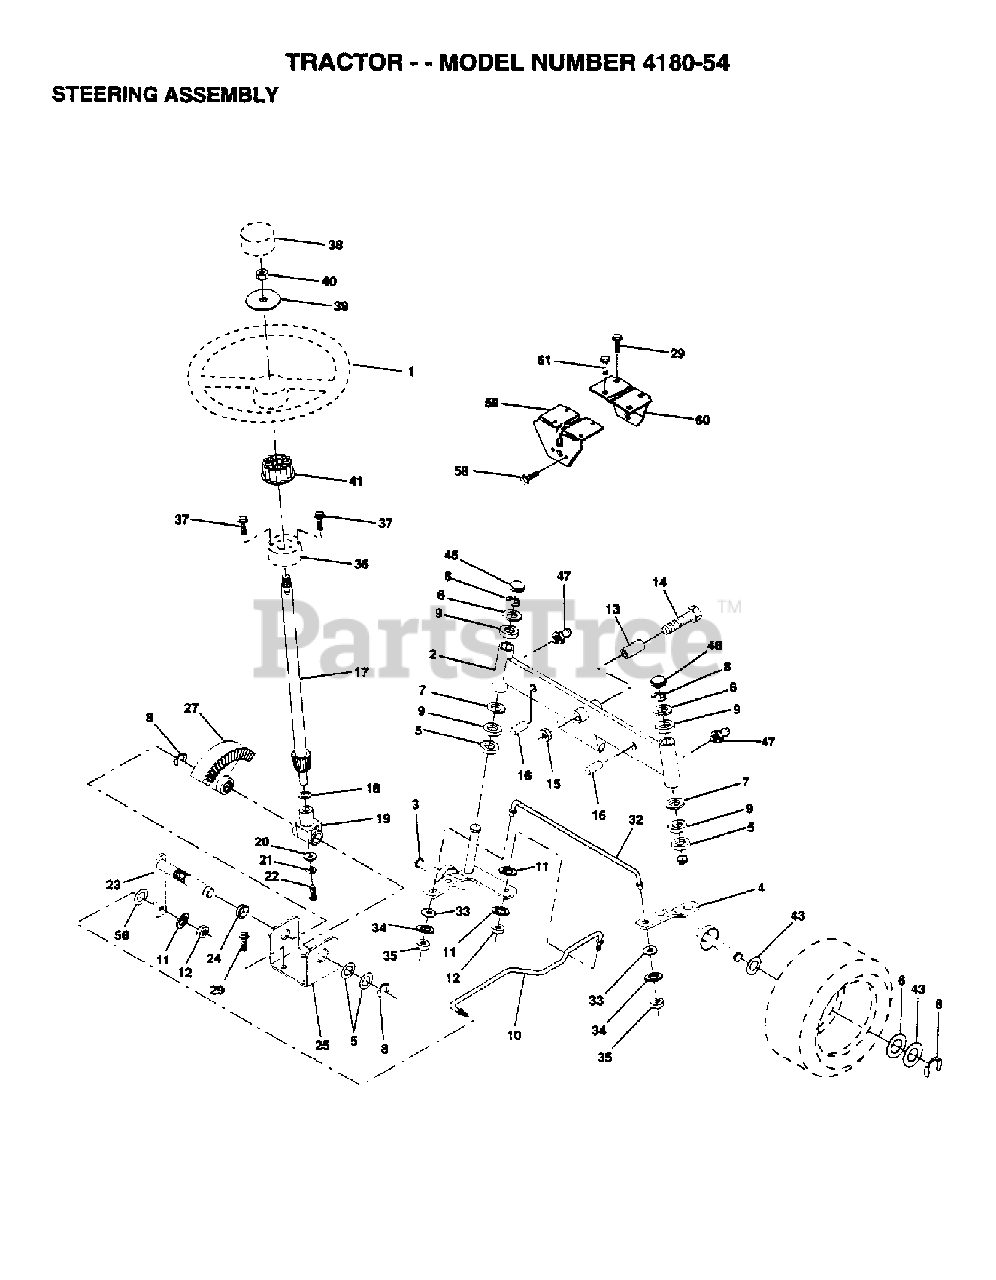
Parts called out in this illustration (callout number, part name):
1	Steering Wheel
2	AXLE ASSY
5	WASHER THRUST
8	RING CLIP
9	BEARING.STEERING.COLUMN
10	DRAG LINK
11	WASHER, LOCK 3/8
12	NUT
15	LOCK NUT
17	SHAFT ASS'Y STEER
18	THRUST WASHER
19	SHAFT,SUPPORT
20	WASHER
21	LOCKWASHER
23	SHAFT,PITMAN
24	NYLINER T (7283A)
25	BRKT,STEERING
27	GEAR.SECTOR
33	WASHER M
34	LOCKWASHER
35	LOCKNUT
36	BUSHING STRG 3/4
37	SCREW
38	INSERT STR WHL
40	NUT.HEX.1/2-20
46	CAP.SPINDLE.BLACK
47	ZERK.GREASE.TAPERED
56	WASHER
58	SCREW LT
59	SUPPORT-SADDLE LT NLA
60	SUP-SADDLE FRT LT
61	SCREW SPECIAL
